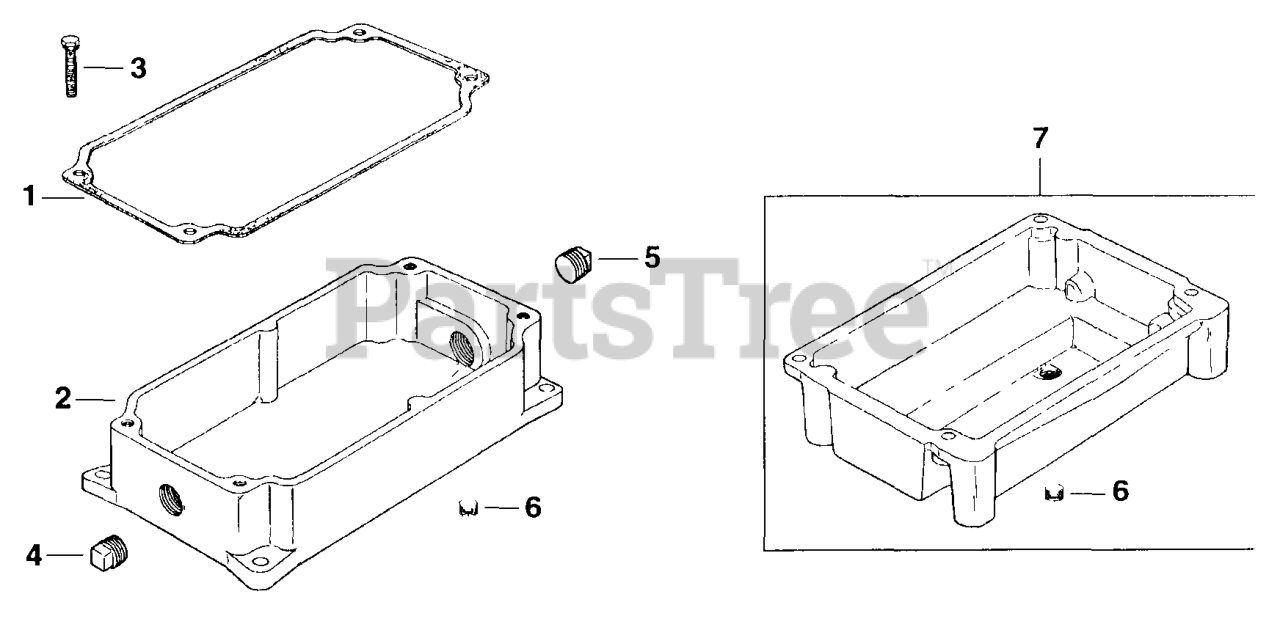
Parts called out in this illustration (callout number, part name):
1	GASKET, OIL PAN
2	PAN - DISCONTINUED
3	SCREW, SEMS 3/8-16X1-1/4" - DISCONTINUED
4	PLUG,PIPE SQ HD 3/4" USE 25 139 56-S
6	PLUG,PIPE 1/2 NPTF SQUARE HD USE 25 139 54-S
